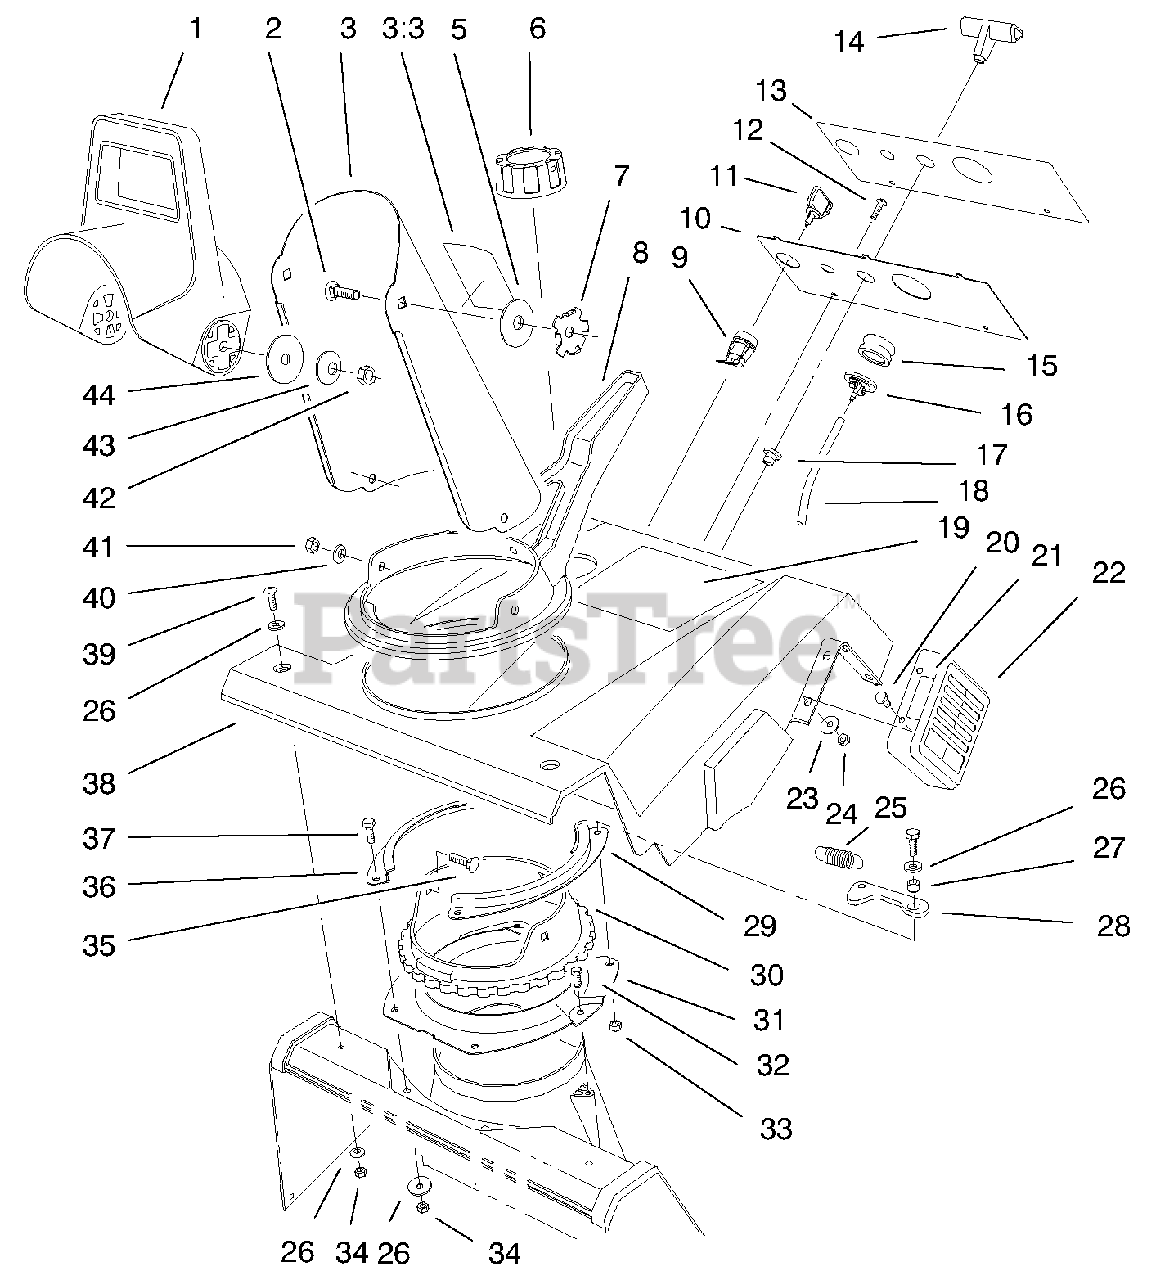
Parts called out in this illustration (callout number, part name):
1	Chute-Deflector
2	Screw-CARR
3	ASM-Chute w/Decal
3:3	Decal-Danger Discharge
5	Washer-Rubber
6	ASM-Gas Cap
7	Plate-Friction
8	Chute-Handle
9	On-Off Switch
10	Control Panel (only on: 28220)
10	Control Panel (only on: 28222)
12	Screw-Self TAP
13	Decal-Control Panel (only on: 28222)
13	Decal-Control Panel (only on: 28220)
14	Handle-Starter
15	Bulb-Primer
16	Body-Primer
17	Starter Rope Guide
18	Primer Hose
19	Decal-320 Recoil (only on: 28220)
19	Decal-320 Electric (only on: 28222)
20	Screw-HWH
21	Decal-Hot
22	Muffler Guard
23	Washer-Flat
24	Nut-Lock Ni
25	Spring-Detent
26	Washer-Flat
27	Rotor Bld Spacer
29	LH Chute Ring Retr
30	Gear Ring, Chute
31	Chute Supt Ring
32	Plastite Screw
33	Nut-Lock Ni
34	Nut-Lock Ni
35	Screw-HH
36	RH Chute Ring Retr
37	Screw-HH
38	Upper Shroud
39	Screw-PPH
40	Washer-Flat
41	Nut-Keps
42	Nut-Lock Ni
43	Washer-Belleville
44	Washer-Flat
